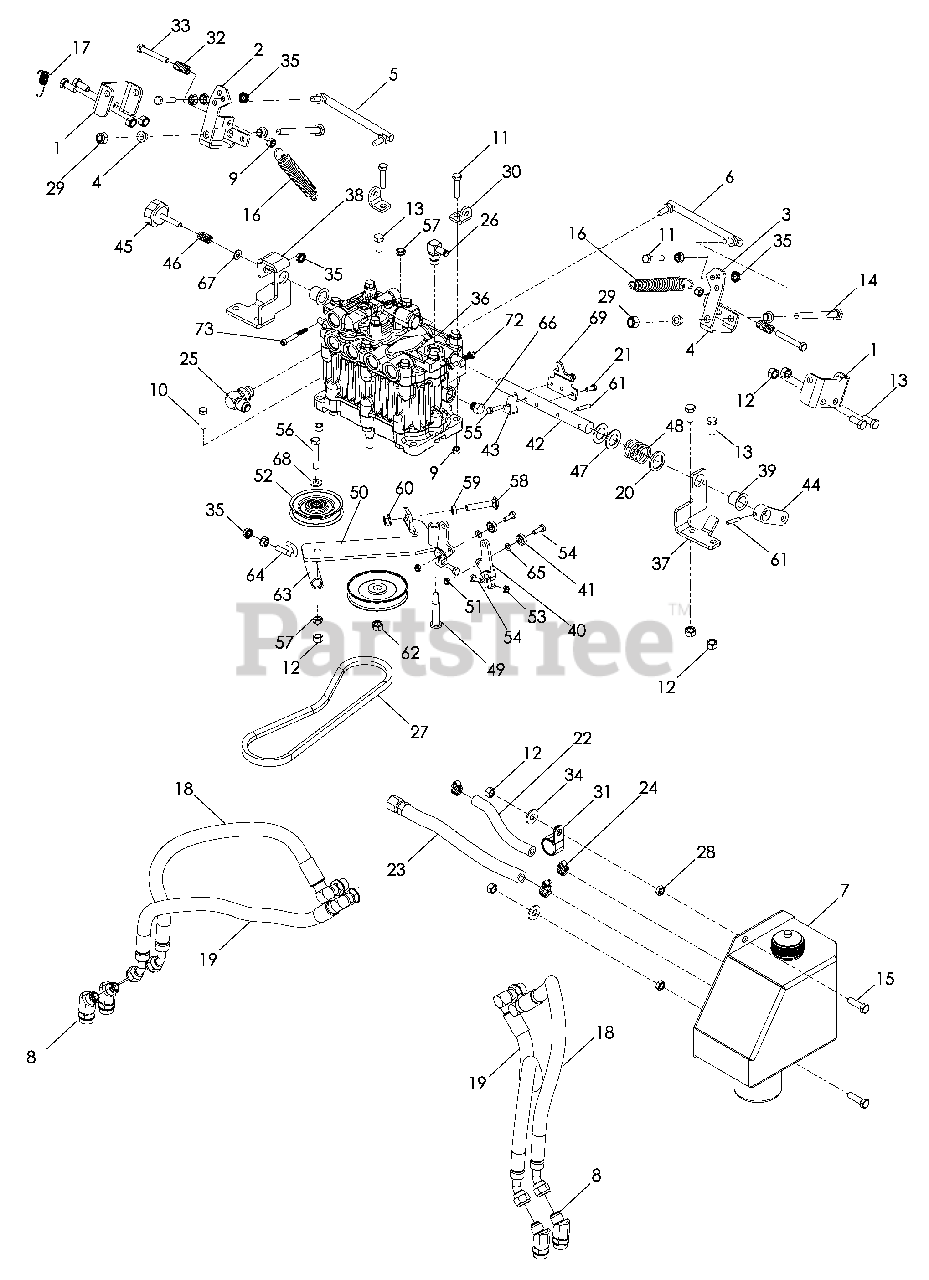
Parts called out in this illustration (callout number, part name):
2	BELLCRANK, RH
3	BELLCRANK, LH
4	BEARING, FLANGE
5	LINK, CONTROL, RH
6	LINK, CONTROL, LH
7	RESERVOIR
8	ELBOW 45° STRAIGHT THD
9	NUT 5/16-18 HEX NYLOC
10	HCS 5/16-18 x 1¼
11	HCS 5/16-18 x 1½
12	NUT 3/8-16 HEX NYLOC
13	Hcs3/8-16 x 7/8
14	HCS M10-1.58 x 100 GR 8.8
15	HCS 3/8-16 x 1¼
17	SPRING, EXTENSION
20	WASHER, FIBER
21	HCS M6-1.0 x 16MM GR 8.8
22	HOSE, RETURN
23	HOSE, SUCTION
24	CLAMP, HOSE
25	ELBOW 90°
26	FITTING 90°
28	Nut3/8-16 Hex Jam
29	NUT, M10-1.5 NYLON RING
30	BRACKET, SPRING
33	HCS 5/16-18 x 2¼
34	WASHER 3/8 FLAT
35	NUT 5/16-18 HEX WHIZLK
36	PUMP, DUP10S
37	SUPPORT, CAM LH
38	SUPPORT, CAM RH
39	BEARING, FLANGE
40	ARM, HYDRO
41	BEARING, FOLLOWER
42	SHAFT, CAM
43	CAM, TRACKING
44	ARM, SPEED CONTROL
45	KNOB, ADJUSTMENT
46	SPRING, COMPRESSION
47	WASHER, 20MM
48	SPRING, COMPRESSION
49	PULLEY, PUMP
50	IDLER ARM, BLK
51	SHOULDER BOLT
53	NUT ¼-20 HEX THIN NYLOC
54	HCS ¼-20 x ¾
55	HCS M6-1.0 x 30MM GR 8.8
56	HCS 3/8-16 x 2
57	NUT 3/8-16 HEX JAM NYLOC
58	RHSNB 3/8-16 x 2
59	NUT 3/8-16 HEX JAM
60	NUT 3/8-16 HEX WHIZLK
61	ROLL PIN, 6 MM x 30 MM
62	NUT, M10-1.5 L/H HEX
67	WASHER 5/16 SAE FLAT
68	WASHER, 3/8 SAE FLT
69	PLATE, NEUTRAL STOP
70	NUT M8 x 1.25 NYLOC
71	WASHER 5/16 SLW
72	NUT #10-24 HEX NYLOC
73	SCREW #10-24 SCKT HD
